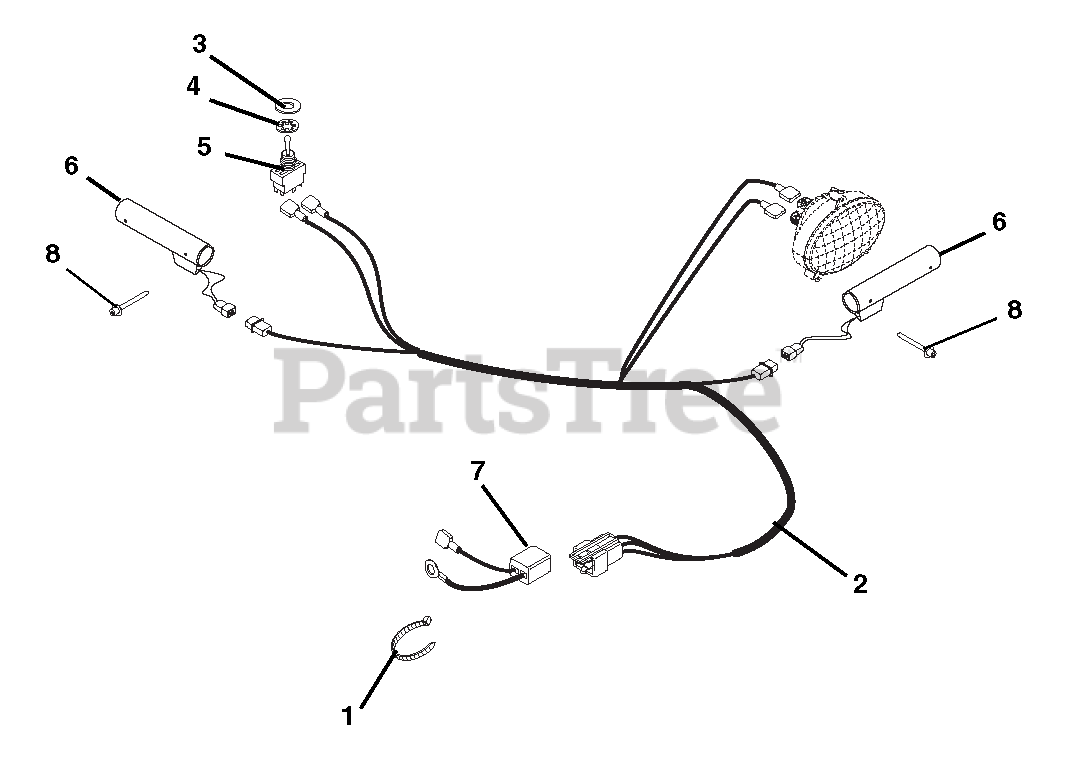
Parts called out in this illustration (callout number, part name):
1	CABLE TIE LG 5-1/2
2	HARNESS, WIRE-LIGHT HANDWARMER
2	HARNESS, WIRE-LIGHT
3	WSHR-FL-STL .505X.875X.024 PL
4	WSHR-LK-INT .563X.040 YWZC
5	SWITCH, ON/OFF
6	HEATED GRIP, MAGURA
7	HARNESS ADAPTER, BRIGGS 9A DC
8	RVT-POP #43 .125X.313 STL ZINC
